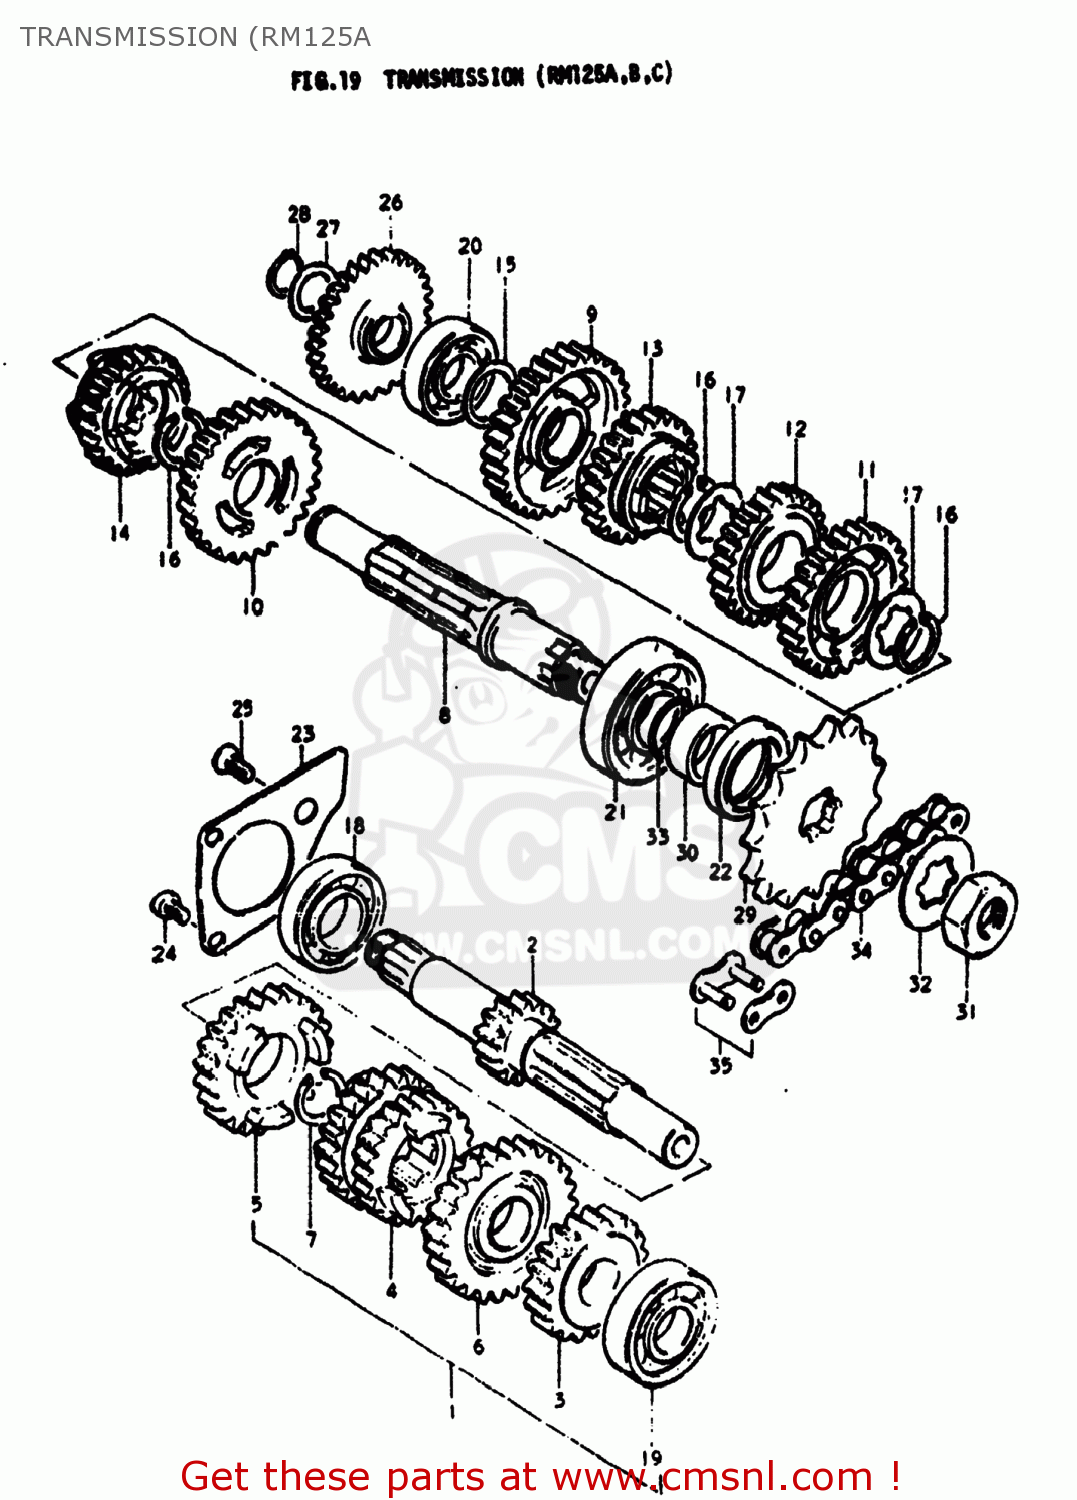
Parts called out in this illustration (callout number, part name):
1	SHAFT,COUNTER
2	SHAFT,COUNTER
3	GEAR,SECOND DRIVE
4	GEAR,THIRD DRIVE
5	GEAR,FIFTH DRIVE
6	GEAR,SIXTH DRIVE
7	CIRCLIP
8	SHAFT,DRIVE
9	GEAR,FIRST DRIVEN
10	GEAR,SECOND DRIVEN
11	GEAR,THIRD DRIVEN
12	GEAR,FOURTH DRIVEN
13	GEAR,FIFTH DRIVEN
14	GEAR,SIXTH DRIVEN
15	WASHER,THRUST
16	CIRCLIP
17	WASHER,LOCK
18	Bearing
19	BEARING
20	BEARING, RH
21	BEARING(20X47X14)
22	SEAL,OIL(25X40X7)
23	PLATE,COUNTERSHAFT BEARING
24	SCREW 6X12
25	SCREW
26	GEAR,KICK STARTER IDLE
27	WASHER,THRUST
28	CIRCLIP
29	SPROCKET,ENGINE
30	SPACER(20X25X12.5)
31	NUT
32	WASHER,LOCK
33	O RING(D:1,ID:19.5)
34	CHAIN ASSEMBLY,DRIVE
35	JOINT ASSEMBLY,CHAIN
